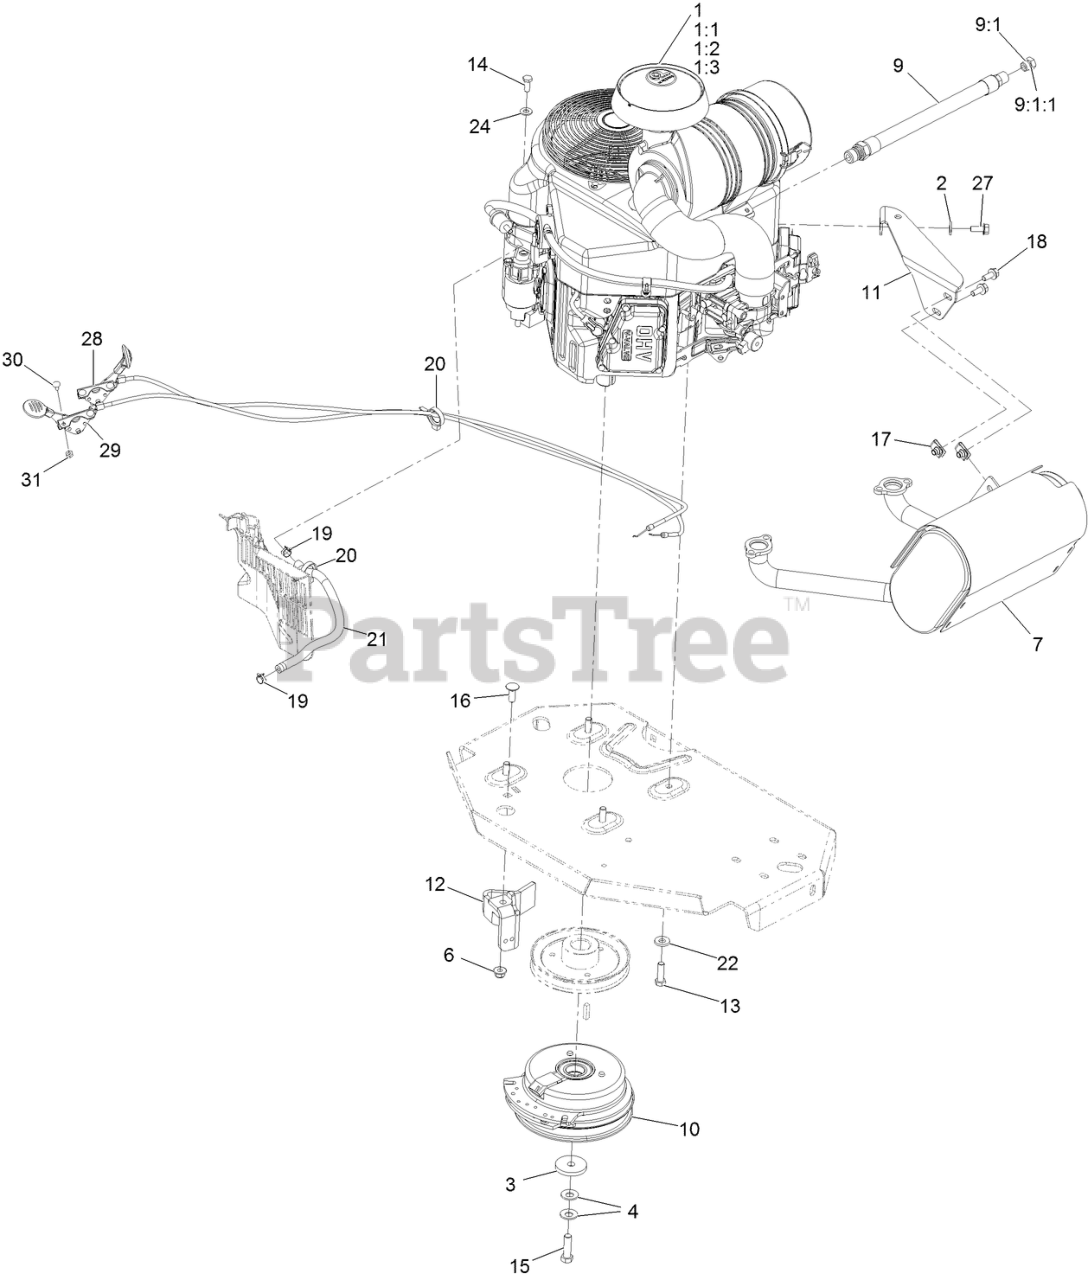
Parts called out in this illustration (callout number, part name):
1:1	Kawasaki 49065-7007 Engine Oil Filter
1:2	Kawasaki 11013-7044 Engine Air Filter
1:3	Kawasaki 11013-7045 Safety Filter
2	WASHER-SPRING
3	WASHER-CLUTCH
4	WASHER-SPRING
6	NUT-HF, NI
7	MUFFLER
9	ENGINE OIL DRAIN HOSE ASM
9:1	PLUG-HH
9:1:1	O-RING
11	BRACKET-MUFFLER
12	CLUTCH-ANCHOR
13	SCREW-HH
14	SCREW-HH
15	SCREW-HH 7/16-20 X 1 1/2 W/LOCTITE
16	SCREW-CARR
18	SCREW-HHF
19	CLAMP-HOSE
20	CLAMP-HOSE
21	HOSE-FUEL
22	WASHER-BELLEVILLE
24	WASHER-PLAIN
27	SCREW-HHF
28	ASM, CHOKE CABLE
29	ASM,THROTTLE CABLE
30	BOLT-CARR
31	NUT-LOCK, NI
